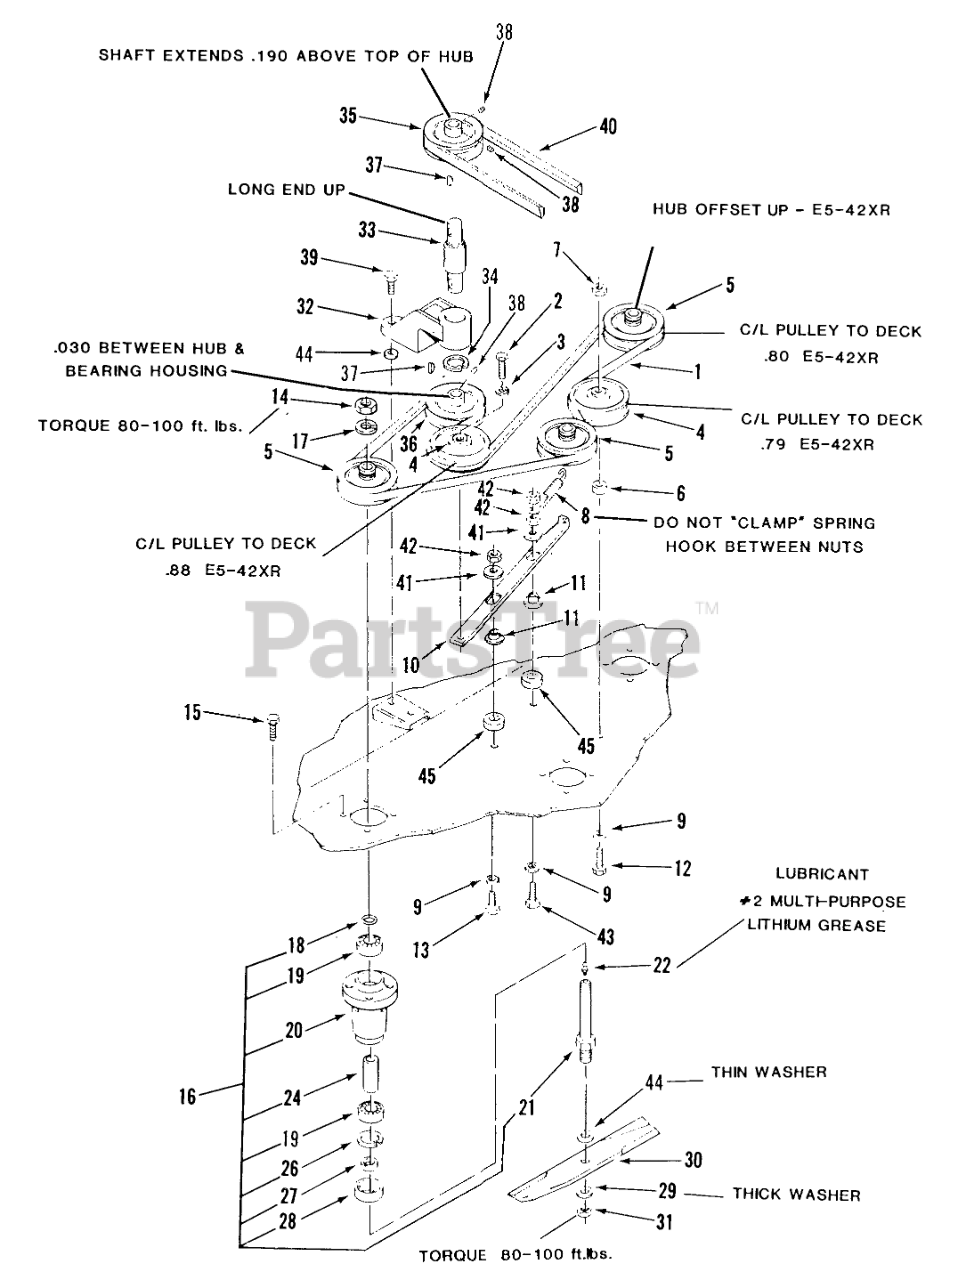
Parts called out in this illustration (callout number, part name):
1	V-BELT
2	BOLT HEX SPECIAL
3	LOCKWASHER
4	Idler Pulley
5	PULLEY
6	SPACER
7	Nut
8	SPRING-EXTENSION
9	WASHER
10	BAR-SLIDER
11	SPACER-BUSHING
12	Bolt
13	Bolt
14	X-REF 3220-6
15	Bolt
16	Spindle Assembly
17	Lockwasher
18	O RING
19	BEARING-BALL
20	HOUSING-SPINDLE
21	Spindle Shaft
22	Zerk
26	Ring-Snap
27	SPACER-BLADE
28	CUP-SPINDLE
29	SpeciaI Washer
30	Blade 14.5 Low Lift
31	X-REF 3220-7
32	HOUSING DRIVE BRG R
33	BEARING-INT SHAFT
34	Snap Ring
35	PULLEY
36	PULLEY-SPLIT
37	KEY-WOODRUFF
38	Set Screw
39	Bolt
40	V-BELT
41	WASHER
42	NUT
43	Bolt
44	Washer
